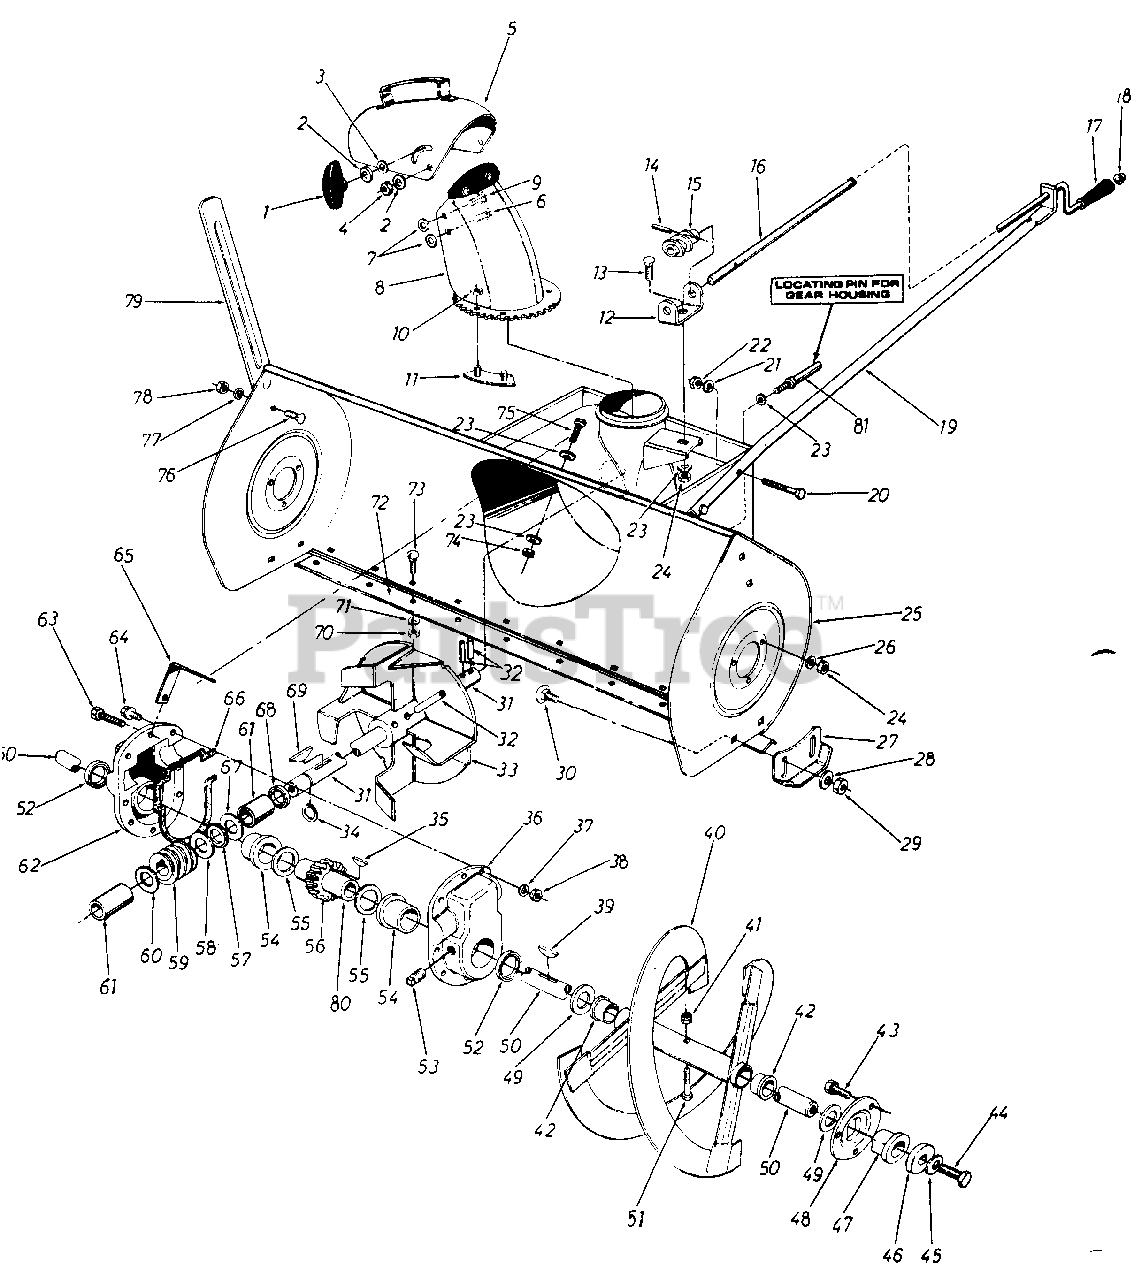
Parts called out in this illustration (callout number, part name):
1	Hand Knob Ass'y.
2	Bell. Wash. .345 I.D. x .88 O.D. x .060
3	Fl.-Wash. .312 I.D. x 1.125 O.D. x .125
4	HexCent. L-Nut5/16-18 Thd.
5	Top Chute Ass'y.
6	Carriage Bolt 5/16-18 x 1.50" Lg.
7	Fl.-Wash. .53 I.D. x 1.25 O.D. x .100
8	Chute Ass'y.
9	Carriage Bolt 5/16 18 x 1.00" Lg.
10	Hex Cent. L-Nut 1/4-20 Thd.
11	Chute Flange Keeper Ass'y.
12	Chute Bracket
13	Carriage Bolt 5/16-18 x .62" Lg.
14	Spring Pin Roll 1/8" Dia. x .75" Lg.
15	Worm- R . H . w h ree Th reads
16	Chute Crank
17	Knob Black 3/8" Dia. Hole
18	Push Nut 3/8" rod.
19	Chute Crank Support Tubing
20	Hex Scr. 3/8-24 x 1.25" Lg.
21	L.-Wash. 3/8" Scr.*
22	Hex Ins. Jam L.-Nut 3/8- 24 Thd.
23	Bell.-Wash. .345 I.D. x .88 O.D. x .060
24	Hex Nut 5/16-18 Thd.
25	Blower Housing Assembly
26	L-Wash. 5/16" Scr.
27	Slide Shoe
28	Bell. Wash. .400 I.D. x .88 O.D. x .060
29	Hex Nut 3/8-16 Thd.
30	Carriage Bolt 3/8-16 x .75" Lg.
31	Blower Axle
32	Spring Pin Spiral 5/16" Dia. x 1.75" Lg.
33	Blower Fan Ass'y.
34	Snap Ring for .875" Dia. shaft
35	#91 Woodruff Key 1/4" x 3/4" Dia.
36	Gear Housing Half-L.H.
37	L.-Wash. 5/16" Scr.
38	Hex ins. L.-Nut 5/16-18 Thd.
39	91 Woodruff Key 1/4" x 3/4" Dia.
41	Hex Ins. L-Nut 5/16-18 Thd.
42	Plastic Bushing
43	Hex Sems Scr. 5/16-18 x .75" Lg.
44	Hex Scr. 5/16-18 x .88" Lg. Speco
45	Belleville Wash. .345" I.D. x .88" O.D.
46	Wash. .390 I.D. x 1.75" O.D. x 3/16" Thk.
47	Flange Bearing w/flats 1.00" I.D.
48	Bearing Housing
49	Fl-Wash. 1.00" I.D. x 1.75" O.D. x .100
50	Spiral Axle
51	Hex Scr. 5/16-18 x 1.75" Lg.'
52	Oil Seal-1.50" I.D.
53	Sq. Hd. Pipe Plug 3/8" Thd.
54	Flange Bearing 1.503 I.D.
55	Fl.-Wash. 1.50" I.D. x 2.0" O.D. x .030
56	Double Threaded Worm Gear- L. H.
57	Thrust Bearing .88" I.D.'x 1.44" O.D.
58	Fl.-Wash. .88" I.D. x 1.5" O.D. x .030
59	Double Threaded Worm-L.H.
60	Fl-Wash. .88 I.D. x 1.4" O.D. x .155
61	Sleeve
62	Gear Housing Half-R.H.
63	Hex Scr. 5/16-18 x 1.25" Lg.
64	Hex Scr. 5/16-18 x 1.00" Lg.
65	Gear Housing Support Brkt
66	Rubber Gasket
67	Fl.-Wash. .88" I.D. x 1.4" O.D. x .155
68	Oil Seal. .875" I.D.
69	#9 Hi-Pro Key 3/16" x 3/4" Dia.
70	Hex Nut 5/16-18 Thd.
71	L.-Wash. 5/16" Scr.
73	Carriage Bolt 5/16-18 x .75" Lg.
74	Hex Nut 5/16-18 Thd.
75	Hex Scr. 5/16-18 x .75" Lg.
76	Carriage Bolt 5/16-18 x .62" Lg.
77	L.-Wash. 5/16" Scr.
78	Hex Nut 5/16-18 Thd.
79	Guide Blade
80	Worm Gear Shaft
81	Stud 3/8-16 x 2.75" Lg.
